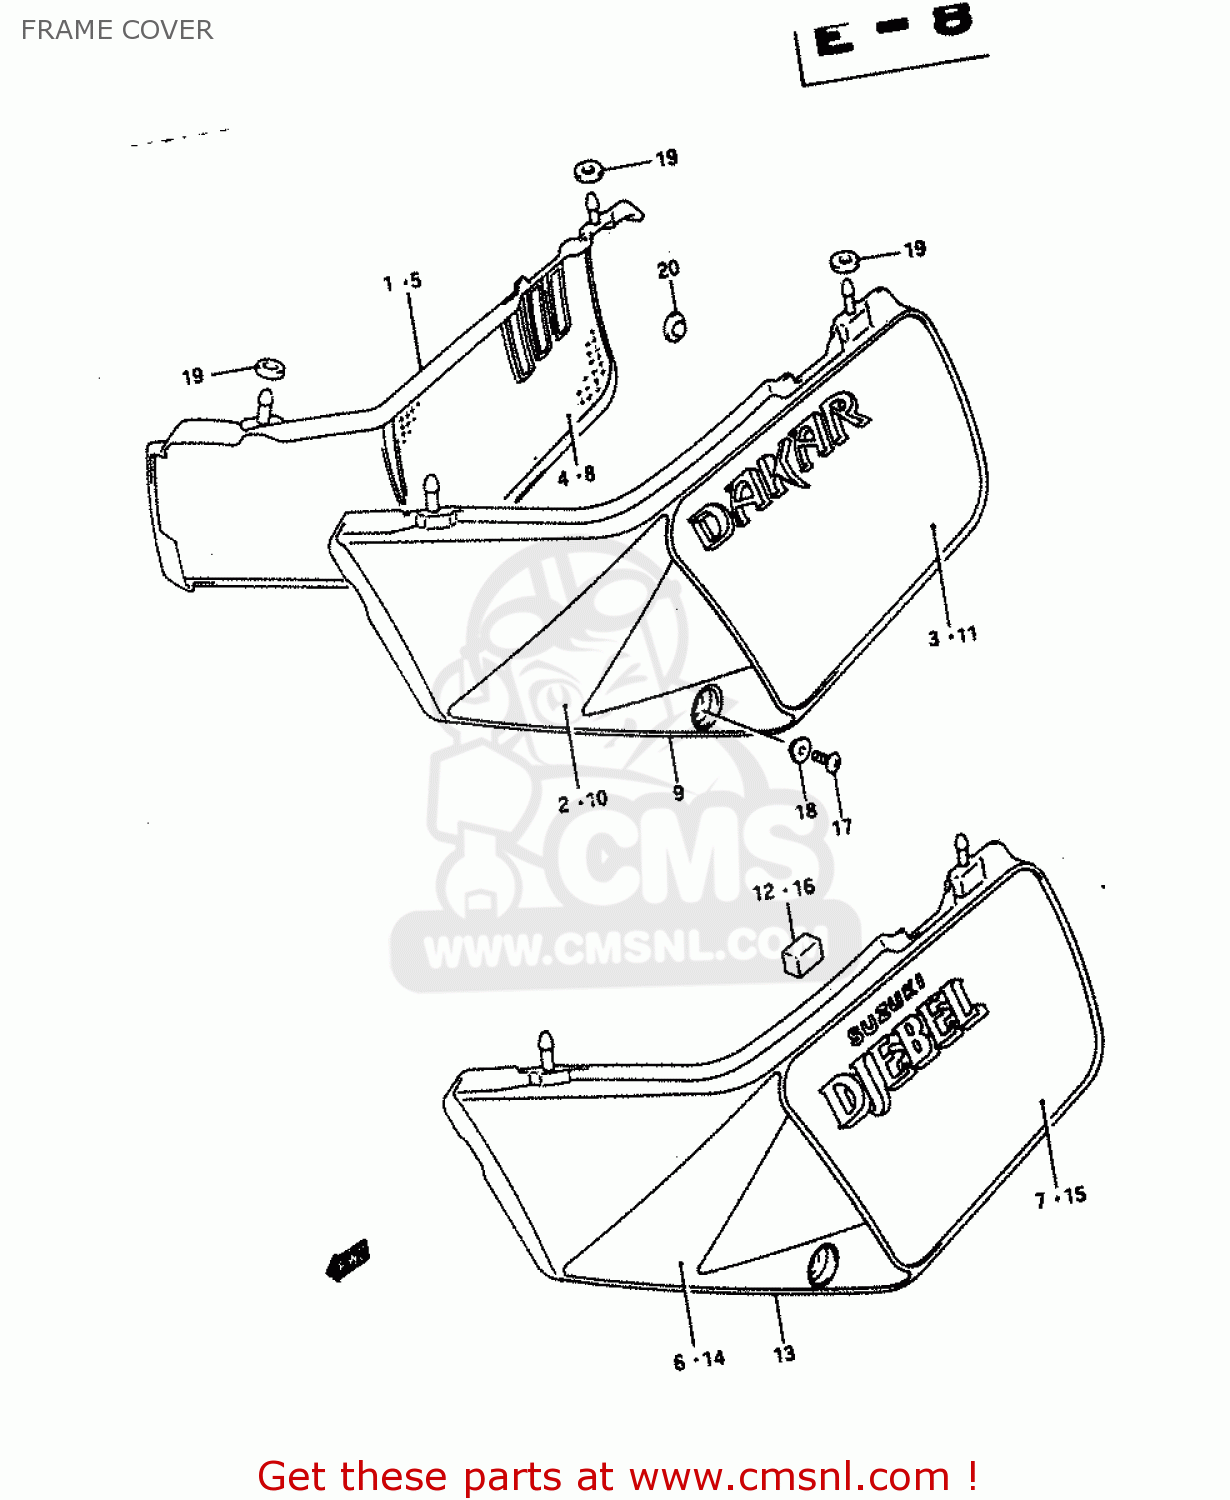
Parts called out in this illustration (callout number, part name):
1	COVER COMP,SIDE,RIGHT
2	TAPE, FRONT RH
3	TAPE, REAR RH
4	SHIELD,FRAME COVER,RIGHT
5	COVER, FRAME RH (WHITE)
6	TAPE, FRONT RH
7	TAPE, REAR RH
8	SHIELD,FRAME COVER,RIGHT
9	COVER,SIDE,L(WHITE)
10	TAPE, FRONT LH
11	TAPE, REAR LH
12	CUSHION,FRAME COVER
13	COVER, FRAME LH (WHITE)
14	TAPE, FRONT LH
15	TAPE, REAR LH
16	CUSHION,FRAME COVER
17	SCREW 6X12
18	WASHER
19	CUSHION,SIDE COVER BOSS
20	CUSHION
